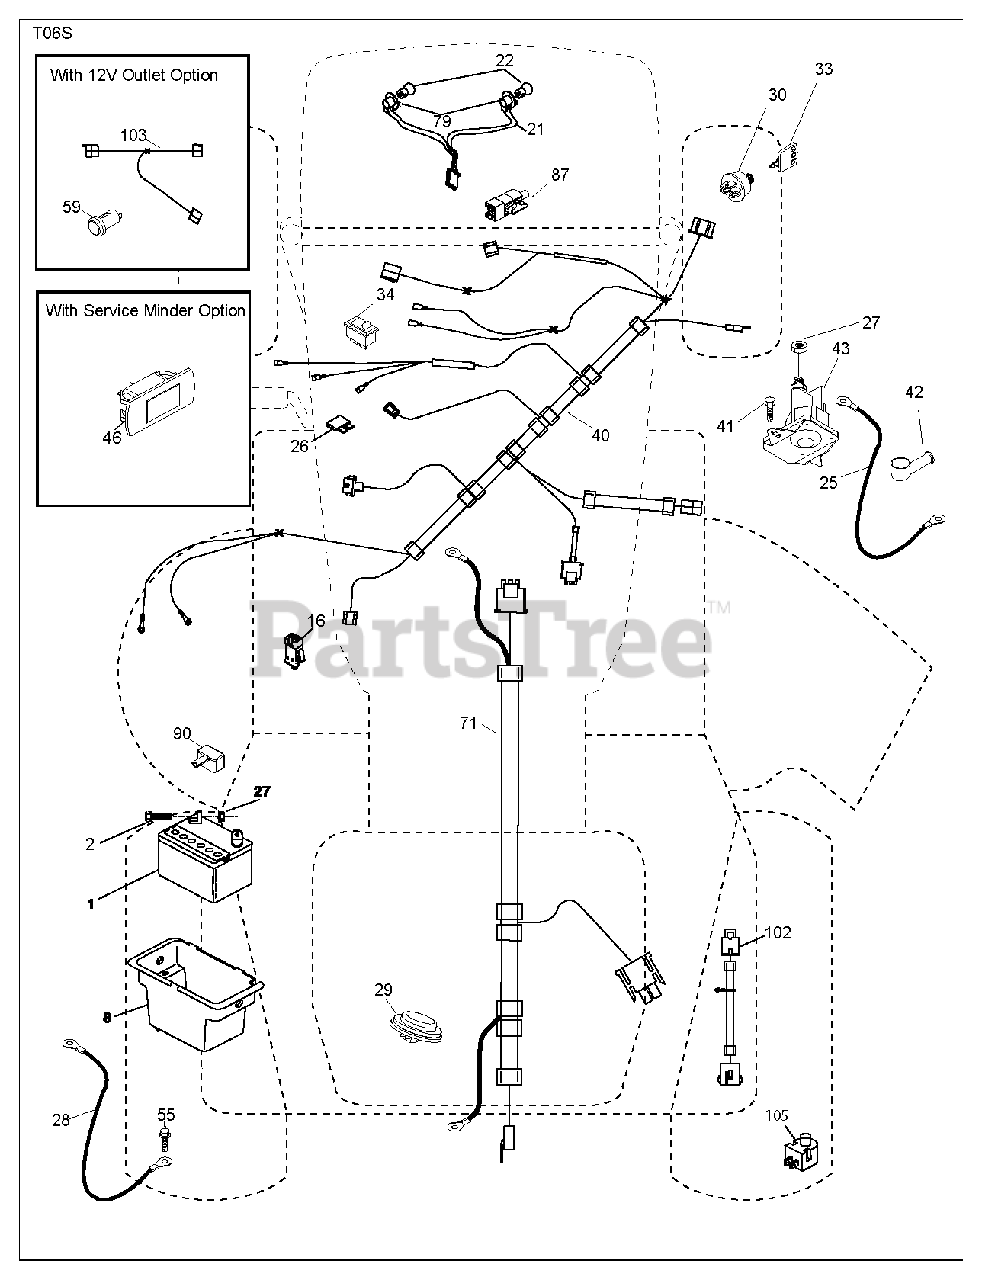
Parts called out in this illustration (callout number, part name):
1	REPL BY 532 12 38-99
8	BOX.BATTERY.MNT.REAR.L
16	SWITCH INTERLOOK PUSH-IN
21	HARNESS.LIGHT W/4152J BULBS
25	CABLE.STARTER.6GA.BL/RED.14.
27	NUT
28	CABLE.BLACK.18"REAR.BA
29	SWITCH.SEAT.DELTA.OPC.
30	SWITCH.IGN.DELTA.W.LGH.ROS
33	KEY.CHAIN.BLISTER.PACK.GEN.INT
40	HARNESS IGN. DASH
41	SCREW
42	TERMINAL COVER
43	SOLENOID.W/BRASS.PLUNG
55	SCREW 5/16"
71	HARNESS.IGN.CHASS.TEX.REAR.BAT
79	BULB HOLDER ASM.
87	SWITCH.INTRLCK.CLUTCH.
90	COVER.TERMINAL.BATTERY
102	HARNESS PIGTAIL PCH TEX ROS
105	REVERSE SWITCH
